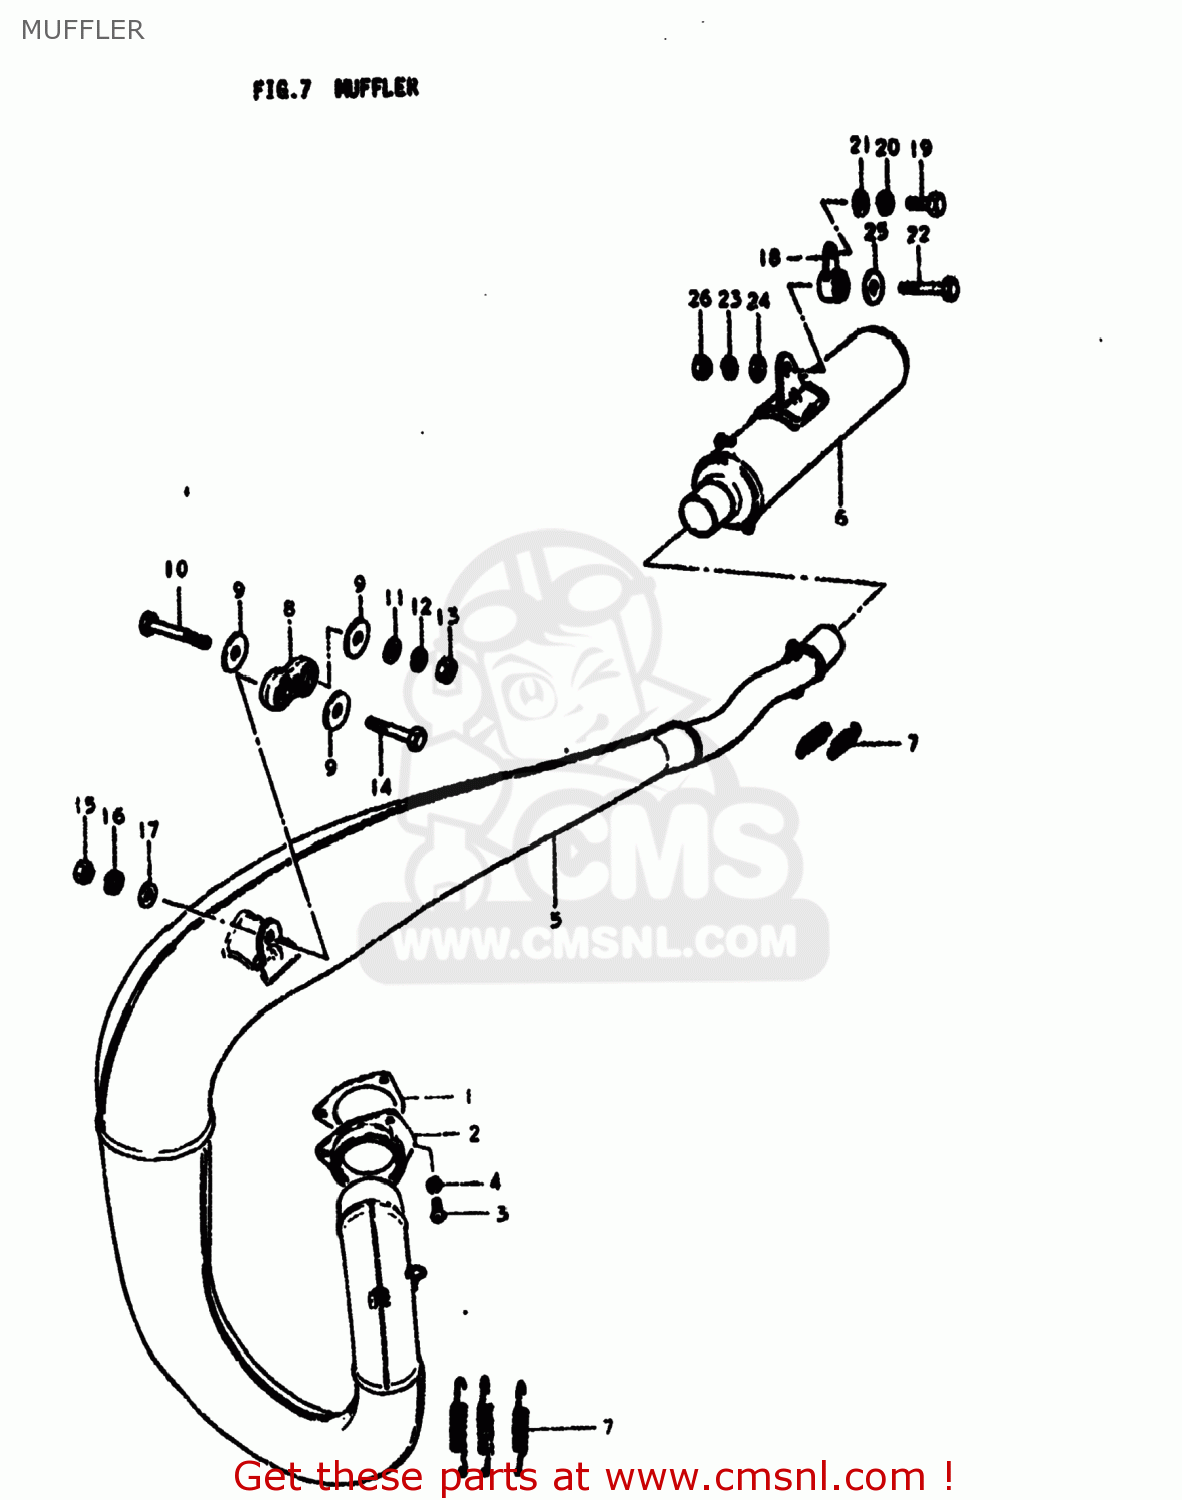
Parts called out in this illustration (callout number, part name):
1	GASKET,EXHAUST PIPE (MCA)
2	FLANGE,EXHAUST PIPE
3	SCREW
4	LOCK WASHER
5	BODY,MUFFLER
6	BODY,MUFFLER
7	SPRING
8	DAMPER,MUFFLER
9	WASHER
10	BOLT 8X55
11	WASHER
12	LOCK WASHER
13	NUT
14	BOLT
15	NUT
16	LOCK WASHER
17	WASHER
18	DAMPER,MUFFLER SUPPORT
19	BOLT
20	LOCK WASHER
21	WASHER
22	BOLT
23	LOCK WASHER
24	WASHER
25	WASHER (8.5X29X1.6)
26	NUT
